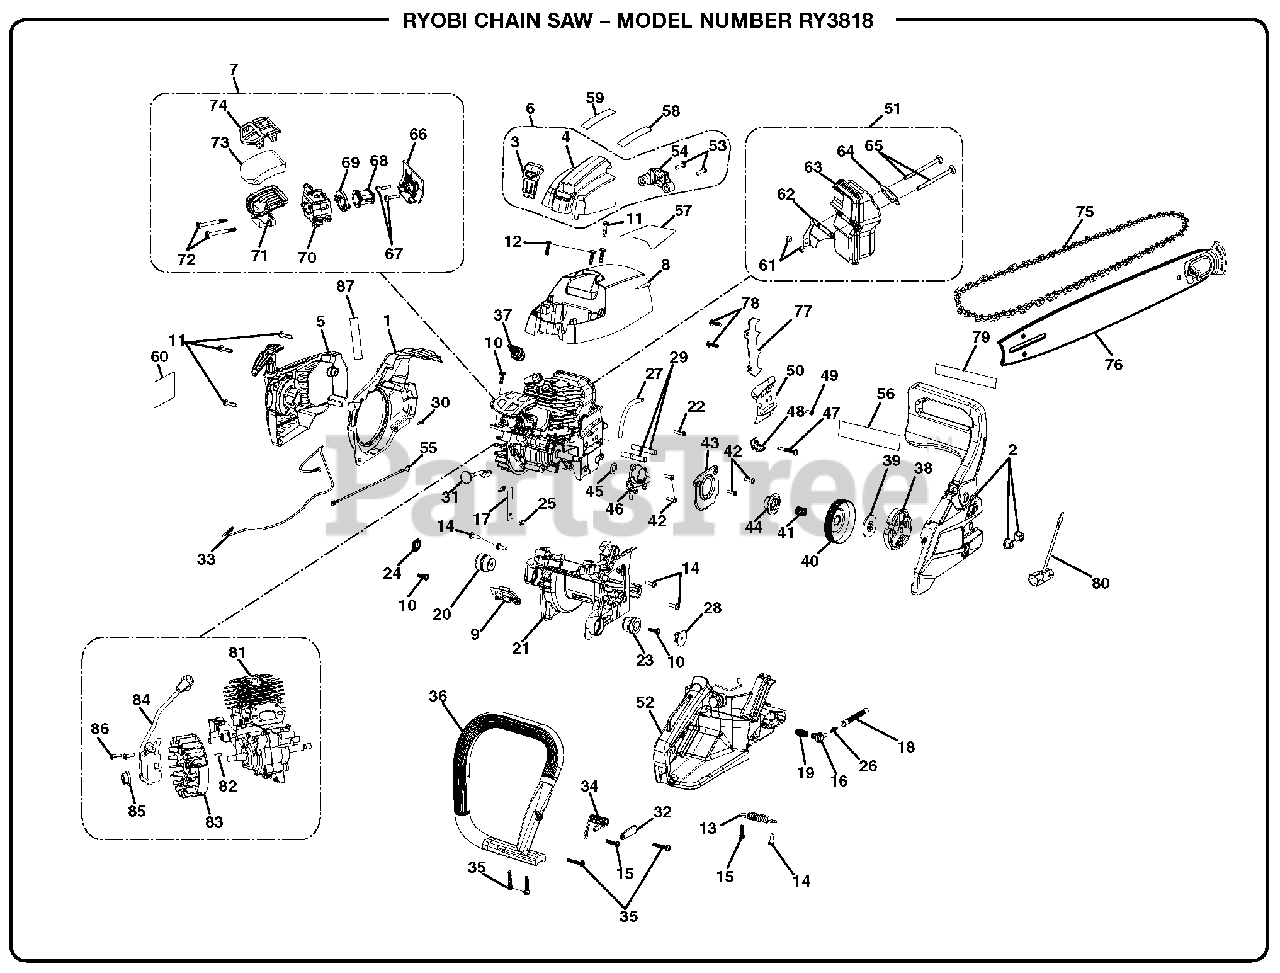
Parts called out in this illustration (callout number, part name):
1	Cylinder Baffle
2	Clutch Cover Assembly
3	Carburetor Cover Latch
4	Carburetor Cover Housing
5	Starter Housing Assembly
6	Carburetor Cover Assembly
7	Intake Assembly
8	Cylinder Housing Assembly
10	Screw (M5 x 16 mm, T25 Torx Pan Hd.)
11	Screw (M5 x 22 mm, T25 Torx Pan Hd.)
12	Screw (M5 x 14 mm, T25 Torx Pan Hd.)
13	Damper Spring
14	Screw (M5 x .8 mm, T25 Torx Pan Hd.)
15	Screw (M5 x 14 mm, T25 Torx Pan Hd.)
16	Oil Filter Grommet
17	Band Stopper
18	Pipe In Oil Pump Rubber
19	Cone Spring
20	Rubber Damper
21	Engine Case
22	Pin (Oil Pump Outlet)
23	Damper Rubber
24	Damper Cap
26	Joint For Pipe In Comp
27	Oil Pump Rubber Tube (Outlet)
28	Damper Cap (T)
29	Bar Stud (5/16-18 x 23.5 mm / 5/16-18 x 18 mm)
30	Hair Pin
31	Choke Rod
32	Damper Plate
33	Lead Wire Assembly (Red)
34	Damper Spring
35	Screw (M5 x 27 mm, T25 Torx Pan Hd.)
37	Spark Plug (BOSCH/WSR6F)
39	Thrust Plate
40	Clutch Drum
41	Clutch Drum Needle Bearing
42	Screw (M4 x 14 mm, T20 Torx Pan Hd.)
43	Oil Pump Cover
44	Oil Pump Drive Gear
45	Washer (ID10.2 x OD18 x 1t)
47	Screw (M4 x 33 mm, T25 Torx Pan Hd.)
48	Chain Catcher
49	Screw (M4 x 12 mm, T20 Torx Pan Hd.)
50	Chain Guard Plate
51	Exhaust Assembly
52	Chassis & Handle Components
53	Screw (M4 x 10 mm, T20 Torx Pan Hd.)
54	Bracket Retainer Latch
55	Lead Wire Assembly (Black)
56	Chain Brake Label (RY3818)
57	Warning Label
58	Starting Label (Right)
59	Starting Label (Left)
60	Starting House Label (RY3818)
61	Nut (M5, Muffler)
62	Muffler Bracket
63	Muffler
64	Gasket (Muffler).
65	Screw (M5 x 14 mm, T25 Torx Pan Hd.)
67	Bolt (M9 x 19 mm, T25 Torx Pan Hd.)
68	Intake Boot
69	Intake Bracket
70	Carburetor Assembly
71	Air Box Base
72	Screw (M5 x 44 mm,T25 Torx Hd. Carburetor)
73	Foam Air Filter
74	Air Filter Retainer
75	18 in. Chain (3/8LP, 62DL)
76	18 in. Guide Bar Assembly
77	Bucking Spike
78	Screw (M5 x 11 mm., T25 Torx Pan Hd.)
79	Pull To Release Brake Label
80	Combination Wrench
81	Short Block
82	Woodruff Key
83	Flywheel Assembly
84	Ignition Assembly
85	Hex Flange Nut (M8)
86	Screw (M4 x 14 mm, T20 Torx Hd.)
87	Combustion Warning Label
